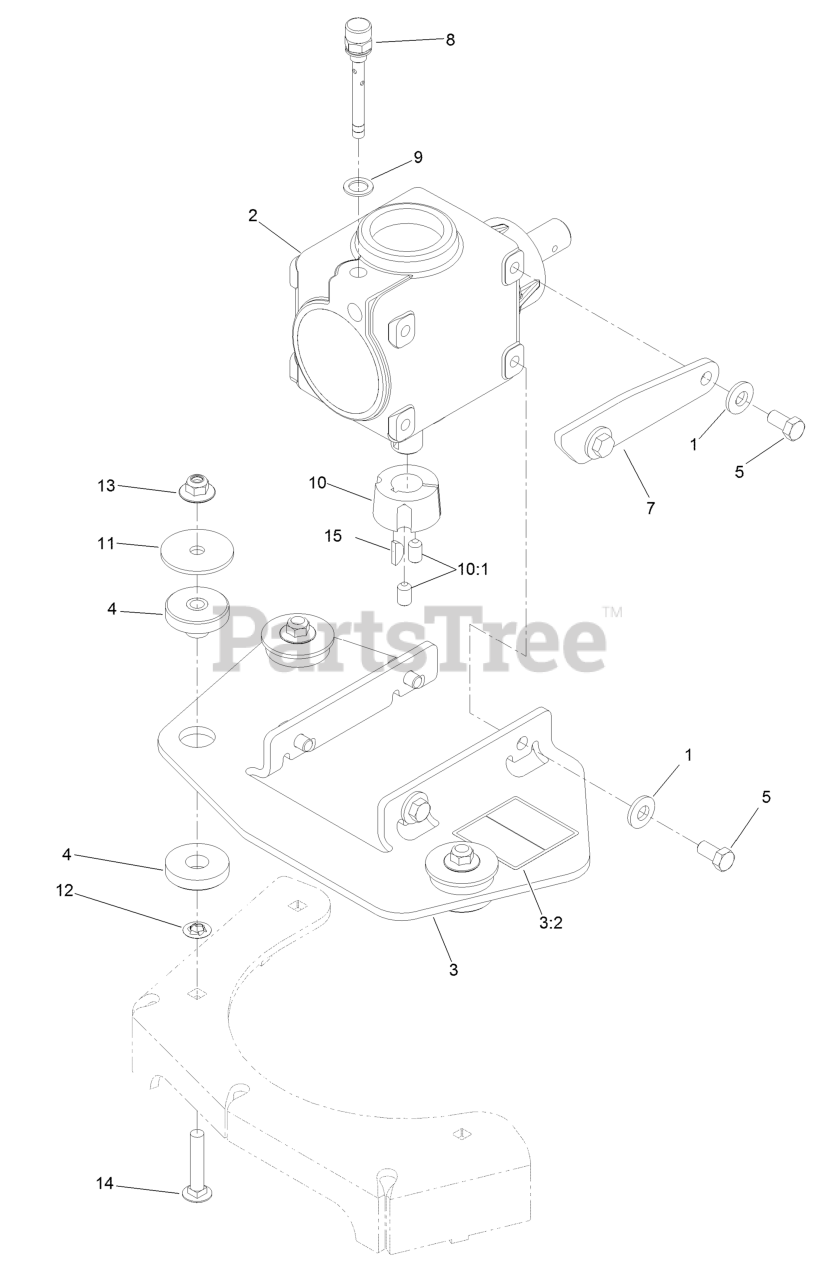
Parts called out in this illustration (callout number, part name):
1	Washer-Belleville
2	Gearbox ASM
3	Mount-Gearbox
3:2	Decal-Hazard, Entanglement
4	Mount-ISO
5	Screw-HH
7	Stop-Gearbox
8	Plug-Breather
10	Bushing-Taperlock
10:1	Screw-Set
11	Washer-Flat
12	Nut-Push
13	Nut-Flange, NI
14	Screw-CARR
15	Key-Woodruff
